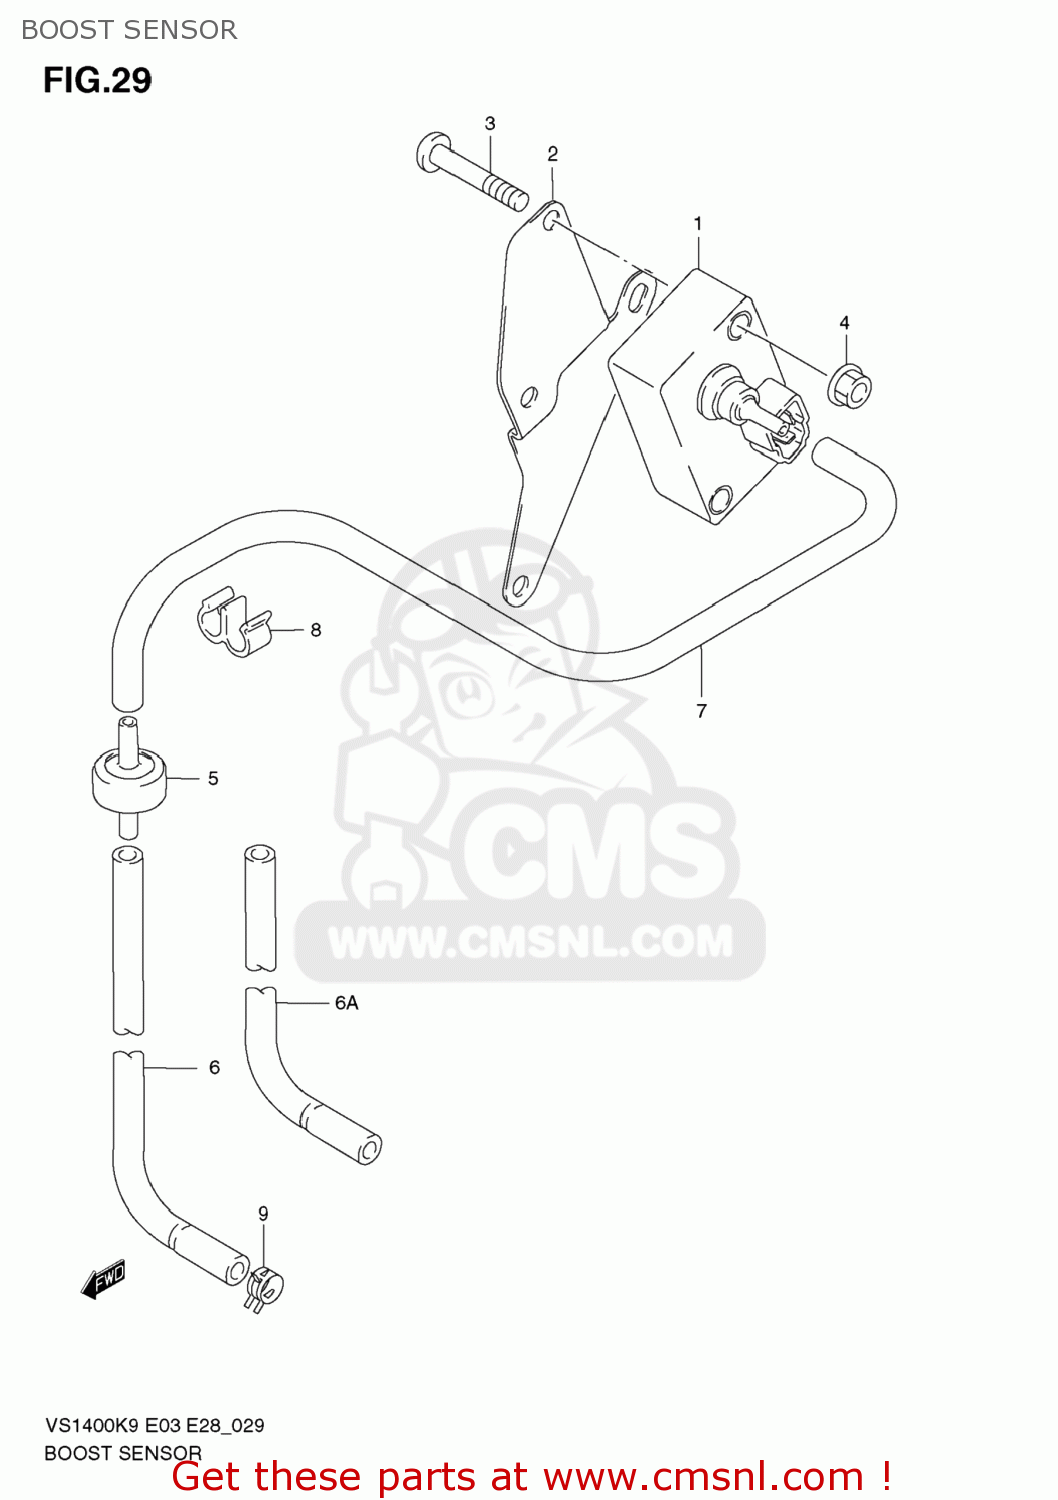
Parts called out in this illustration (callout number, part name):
1	SENSOR ASSY,BOOST
2	BRACKET,BOOST SENSOR
3	SCREW
4	NUT
5	FILTER,VSV
6	HOSE,BOOST NO.1
6A	HOSE(3.5X7.5X2000)
7	HOSE(3.5X7.5X2000)
8	CLAMP
9	CLIP
